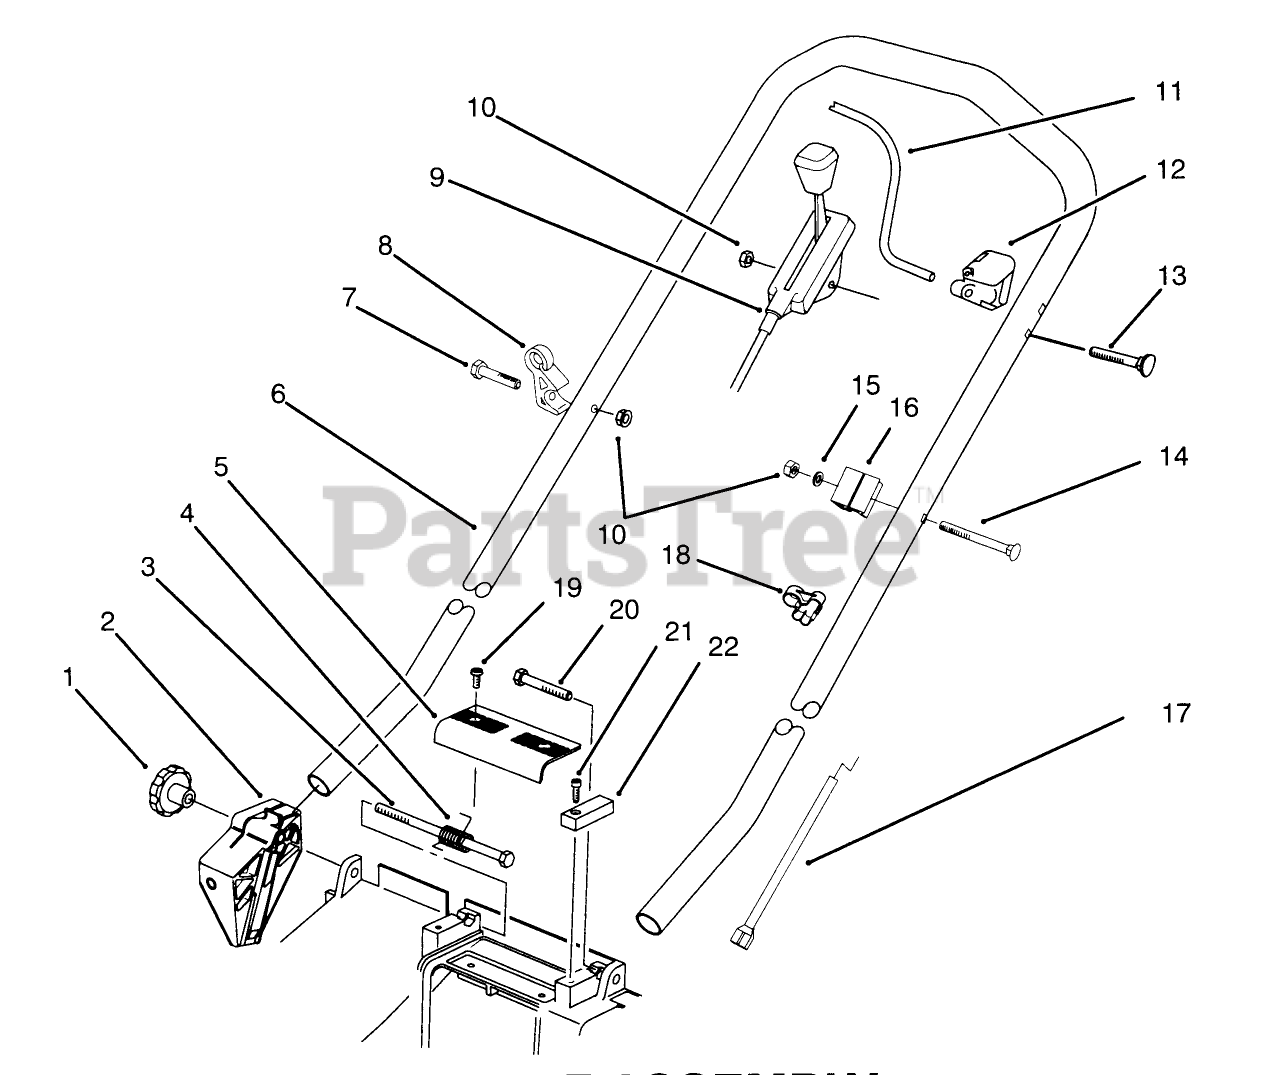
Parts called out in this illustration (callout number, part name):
2	Mount-Handle R.H.
3	BOLT-LONG
4	SPRING-DOOR
5	GRIP-UPPER
6	HANDLE
8	GUIDE - ROPE
9	CONTROL - THROTTLE
10	NUT-LOCK, NI
12	Stop-Pivot
13	SCREW-HANDLE
14	SCREW-HANDLE
15	WASHER-FLAT
16	SUPPORT-CABLE
17	CABLE - BRAKE
19	SCREW-PPH, PLASTITE
